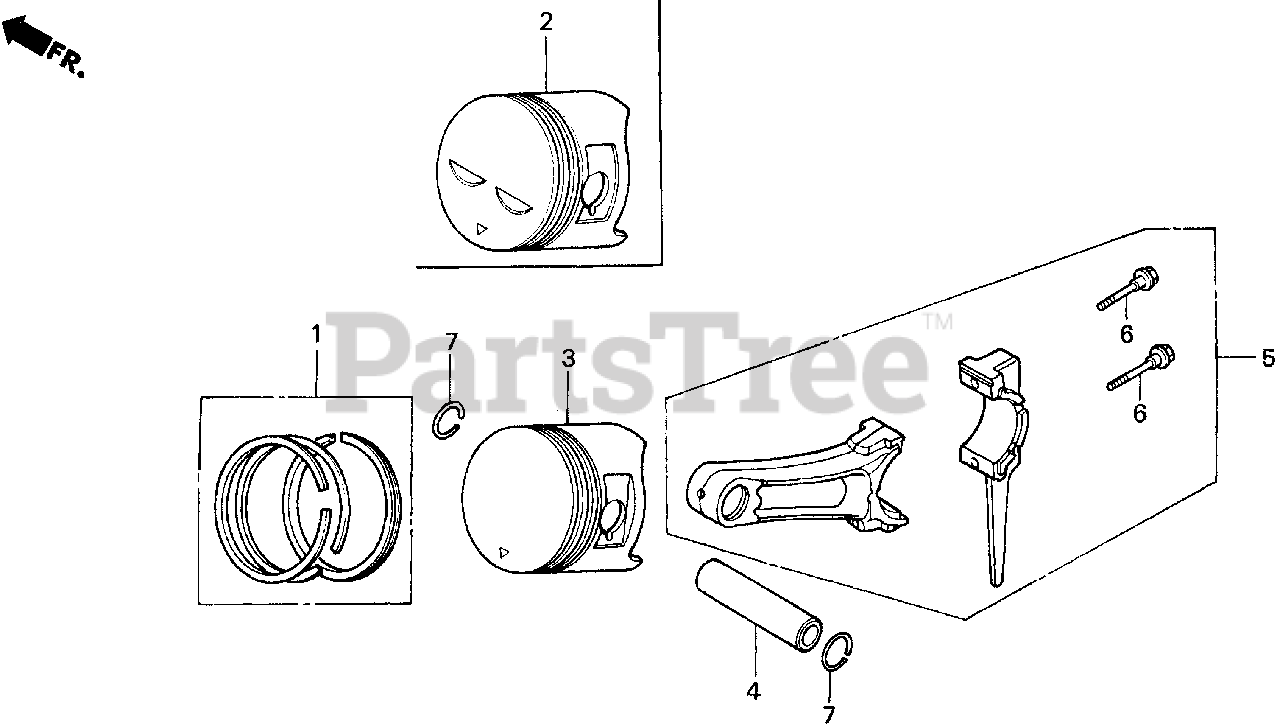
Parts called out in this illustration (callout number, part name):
1	RING SET, PISTON (STD)
1	RING SET, PISTON (STD) (TEIKOKU)
1	RING SET, PISTON (STD) (NIPPON)
1	RING SET, PISTON (OS 0.25) Use up to Engine SN 4081304.
1	RING SET, PISTON (OS 0.25) Use from Engine SN 4081305.
1	RING SET, PISTON (OS 0.50) Use up to Engine SN 4081304.
1	RING SET, PISTON (OS 0.50) Use from Engine SN 4081305.
1	RING SET, PISTON (0.75) Use up to Engine SN 4081304.
1	RING SET, PISTON (0.75) Use from Engine SN 4081305.
2	PISTON (STD)
2	PISTON (OS 0.25)
2	PISTON (OS 0.50)
2	PISTON (0.75)
4	PIN, PISTON
5	ROD ASSY., CONNECTING (STD)
6	BOLT, CONNECTING ROD
7	CLIP, PISTON PIN (18MM)
